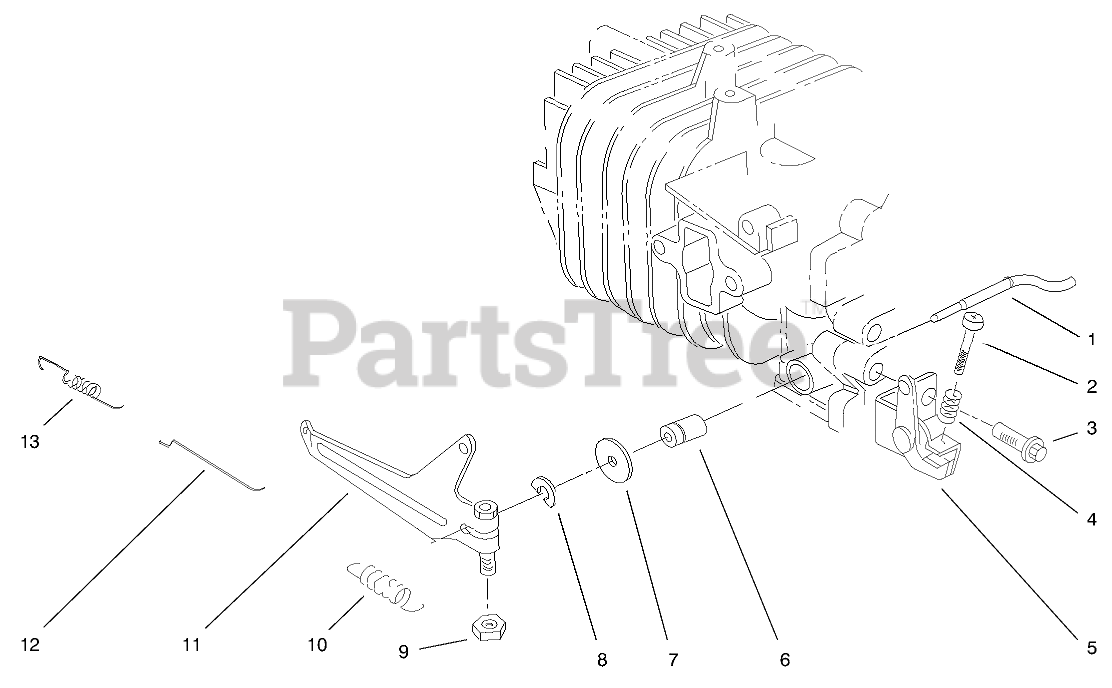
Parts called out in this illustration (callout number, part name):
1	SHAFT
2	SCREW
4	SPRING
5	GOV SPR BRKT
6	SEAL-OIL
7	WASHER
8	E-RING
10	GOV SPRING
11	GOVERNOR ARM
12	CARB ROD
13	CARB SPRING
